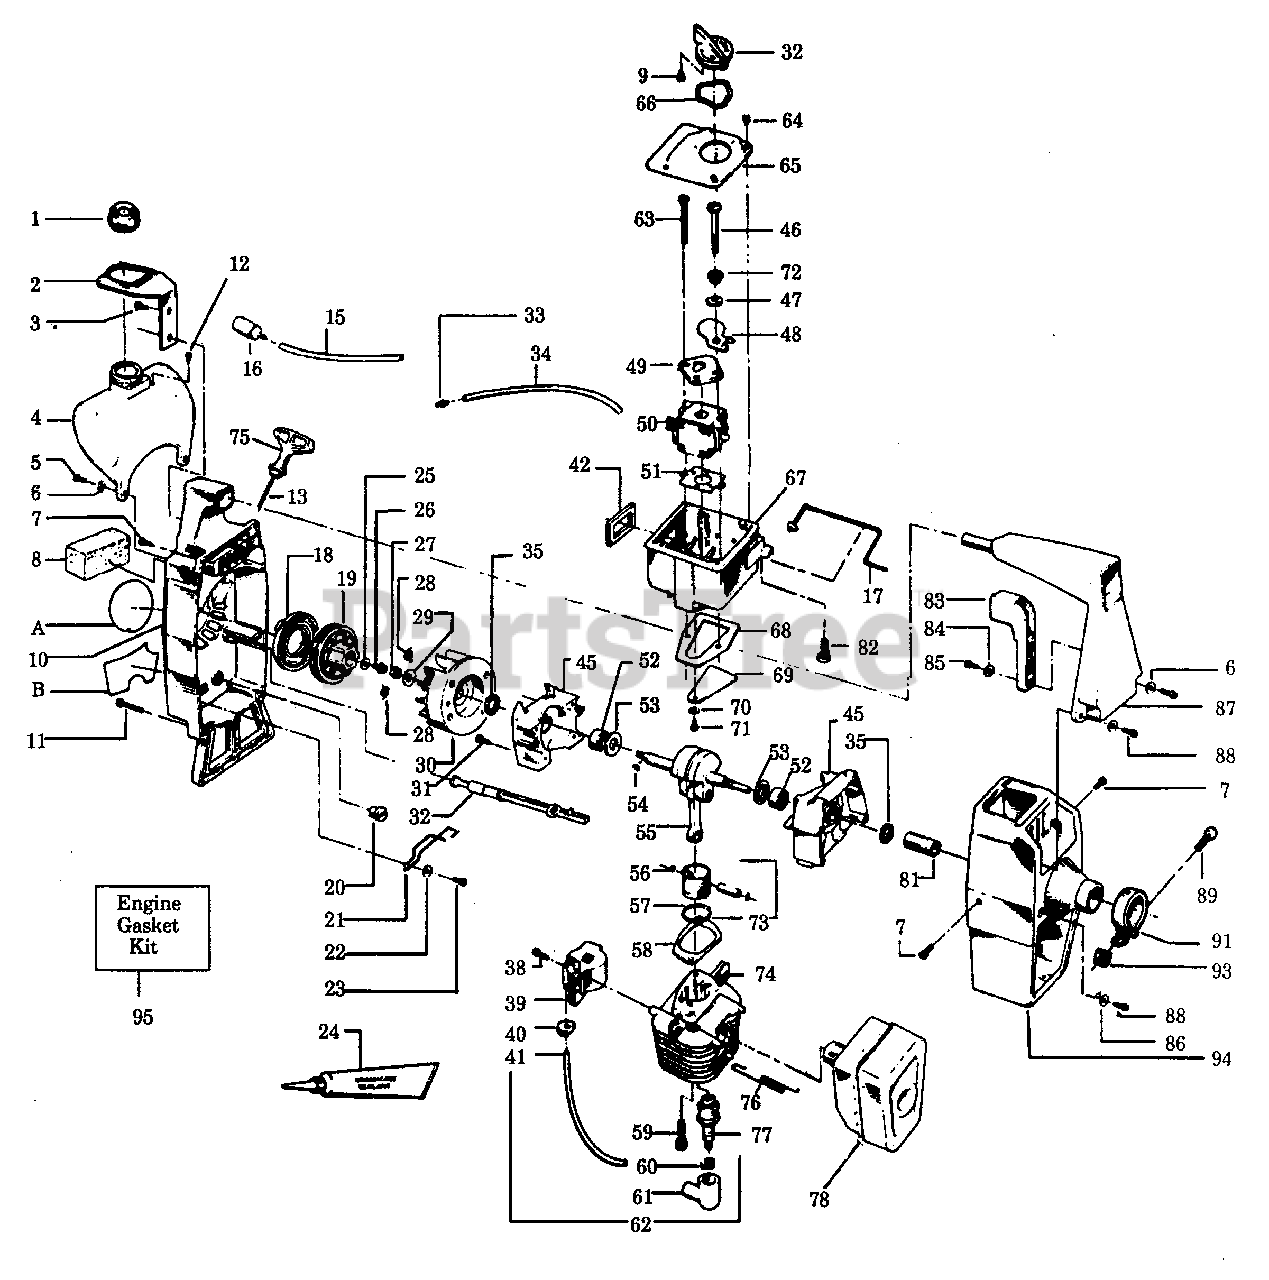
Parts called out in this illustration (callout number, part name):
1	Fuel Cap Ass'y.
2	Fuel Tank Bracket
3	Screw
4	Fuel Tank Ass'y. (Inc.1,12,15 & 16)
8	Air Filter
10	Fan Housing Ass'y.
11	Fan Housing Screw - Bottom
12	Check Valve
13	Rope Kit
15	Line Kit(Bulk 8148)
16	Fuel Pick-Up Ass'y.
17	Throttle Wire
18	Recoil Spring Starter
19	Starter Pulley
20	Kill Switch Button
21	Kill Switch Spring
22	Kill Switch Washer
23	Kill Switch Screw
24	Crankcase Sealant
26	Screw
28	Starter Dog Spring
30	Flywheel Ass'y. (Inc.28)
32	Choke Knob
33	Fuel Line Fitting
34	Carburetor Fuel Line
35	Crankshaft Seal
38	Screw
39	Ignition Module Kit (Inc.21,40,62)
40	Plug Wire Grommet
41	High Tension Lead Wire
42	Carburetor Case Seal
45	Crankcase Ass'y. (Inc.31,35,52)
46	Carburetor Screw
47	Wave Washer
48	Choke Shutter
49	Choke Wire Guide Plate
50	Carburetor
51	Carburetor Gasket
52	Crankshaft Bearing
53	Crankshaft Thrust Washer
54	Flywheel Key
55	Crankshaft & Rod Ass'y.
56	Wrist Pin Retainer
57	Piston Ring
58	Cylinder Gasket
60	Spark Plug Connector
61	Spark Plug Boot
62	High Tension Lead Ass'y. (Inc.41,60 & 61)
63	Carburetor Screw
65	Carburetor Case Cover
66	Wave Washer
67	Carburetor Case Ass'y.
68	Carburetor Case/Crankcase Gasket
69	Reed Valve
70	Reed Valve Washer
71	Reed Valve Screw
73	Piston Kit (Inc.56,57,Pin)
74	Cylinder
75	Starter Handle
76	Muffler Attachment Spring
77	Spark Plug (CJ-14)
78	Muffler Ass'y.
81	Drive Adaptor
83	Throttle Trigger
84	Throttle Washer
91	Shroud Clamp
95	Engine Gasket Kit
A	Starting Instructions Decal
B	Choke/Off Decal
